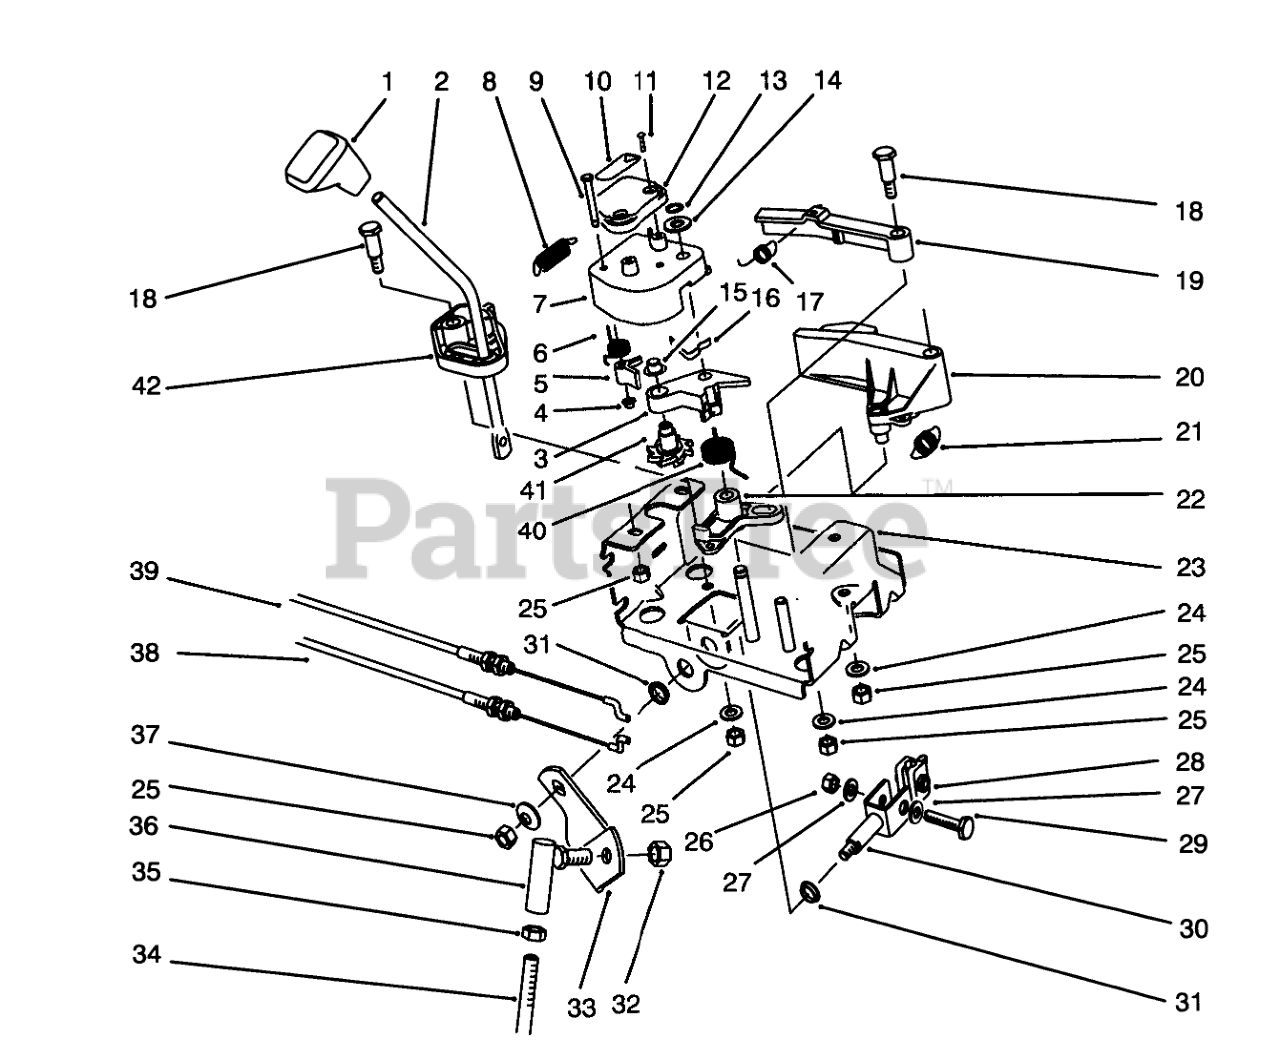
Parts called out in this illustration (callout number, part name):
1	KNOB-SHIFT
2	ROD-SHIFT
3	LEVER-WHEEL, INDEX
4	NUT-PUSH
5	TANG-INDEX
6	SPRING-TORSION
7	LATCH-LEVER
8	SPRING-EXTENSION
9	PIN-TANG
10	DECAL
11	SCREW-PPH
12	COVER-LATCH
13	RING-RETAINING
14	WASHER-THRUST
15	RETAINER-PUSH ON
16	SPRING-FLAT
17	SPRING-EXTENSION
18	SCREW-SHOULDER
19	LEVER-LOCKOUT
20	LEVER-REVERSE
21	SPRING-EXTENSION
22	LEVER-REVERSE, SWITCH
23	Frame-Control
24	WASHER-PLAIN
25	NUT-LOCK, NI
26	NUT-LOCK, NI
27	WASHER-FLAT
28	RETAINER-ROD, SHIFT
29	SCREW-HH
30	CLEVIS ASM
31	BUSHING
32	NUT-LOCK, NI
33	BRACKET-SHIFT
34	ROD-BENT SHIFT, LOWER
35	NUT-HJ
36	JOINT-BALL
37	WASHER-BELLEVILLE
38	CABLE-GEARBOX
39	CABLE-ARM, LATCH
40	SPRING-TORSION
41	WHEEL-INDEX
42	BASE-LOCKOUT
